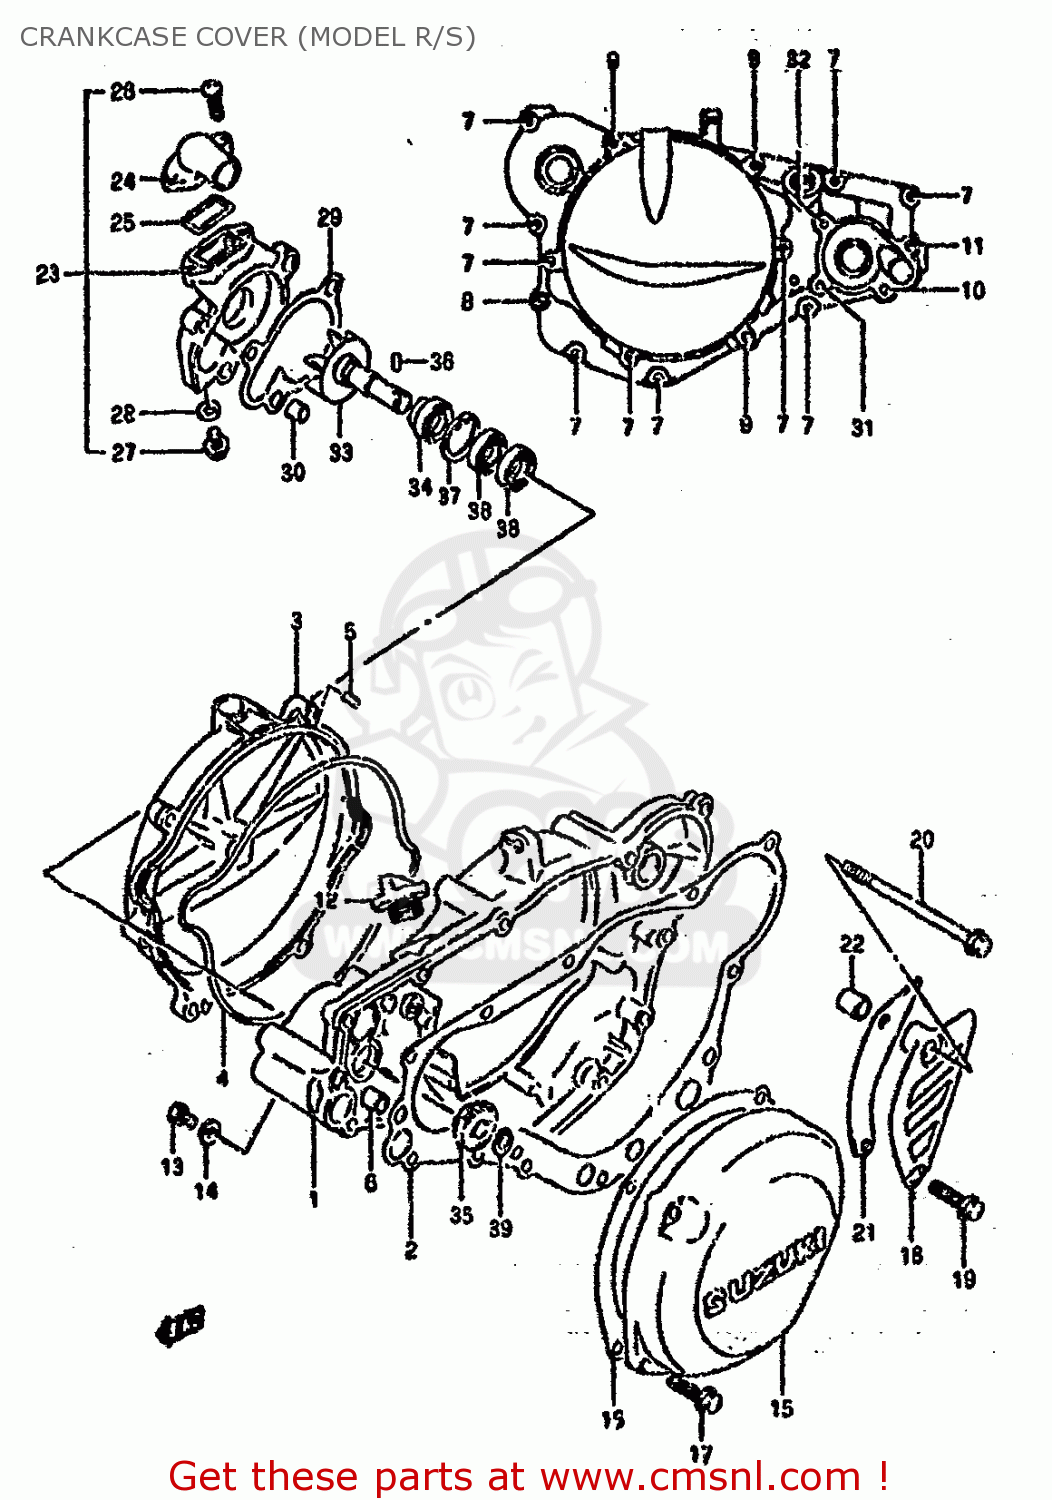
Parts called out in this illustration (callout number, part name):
1	COVER SET,CLUTCH
2	GASKET,CL COVER
3	COVER,CLUTCH OUTER
4	O RING,CLUTCH COVER OUTER
5	PIN
6	PIN
7	SCREW
8	BOLT
9	BOLT
10	BOLT
11	BOLT
12	PLUG SET
13	SCREW(6X10)
14	GASKET(6.2X11X1).2 (NAS)
15	COVER,MAGNETO
16	GASKET,MAGNETO COVER
17	SCREW
18	COVER,ENGINE SPROCKET
19	SCREW
20	BOLT
21	PLATE,FR CHAIN GUIDE(13T)
22	SPACER(6.5X10.5X25)
23	CASE ASSY,WATER PUMP
24	CONNECTOR
25	O RING,WATER PUMP CONNECTOR
26	SCREW
27	BOLT
28	WASHER
29	GASKET,WATER PUMP CASE (NAS)
30	PIN
31	SCREW
32	BOLT,G/S SWITC
33	IMPELLER,WATER PUMP
34	SEAL,WATER PUMP OIL
35	GEAR,WATER PUMP DRIVEN
36	PIN(3X13.8)
37	CIRCLIP
38	BEARING
39	CIRCLIP,10MM
